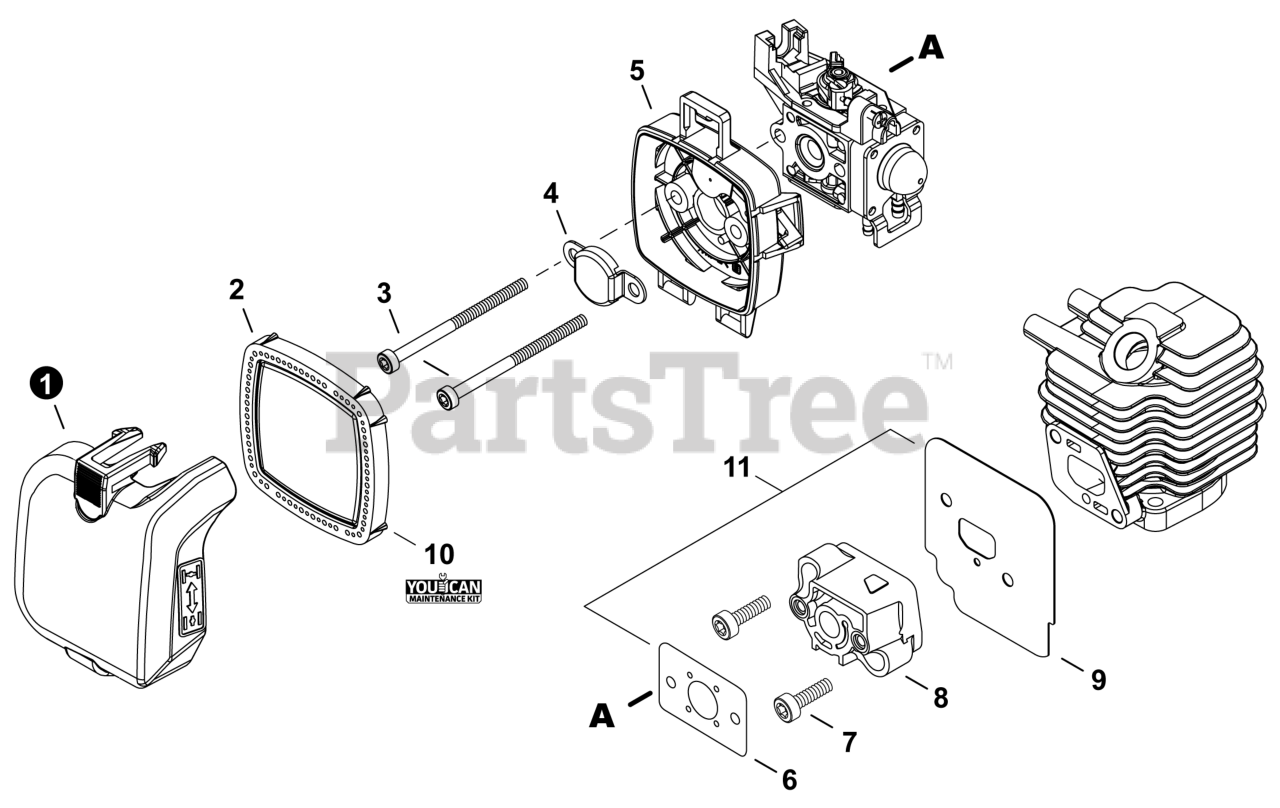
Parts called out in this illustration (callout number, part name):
1	COVER, AIR FILTER
2	FILTER, AIR
3	BOLT, TORX 5x55
4	PLATE, PREVENT
5	CASE, AIR FILTER
6	GASKET, INTAKE
7	BOLT, TORX 5x20
8	INSULATOR, INTAKE
9	HEAT SHIELD, INTAKE
10	TUNE-UP KIT - YOUCAN™
11	GASKET KIT: ENGINE, INTAKE, EXHAUST
